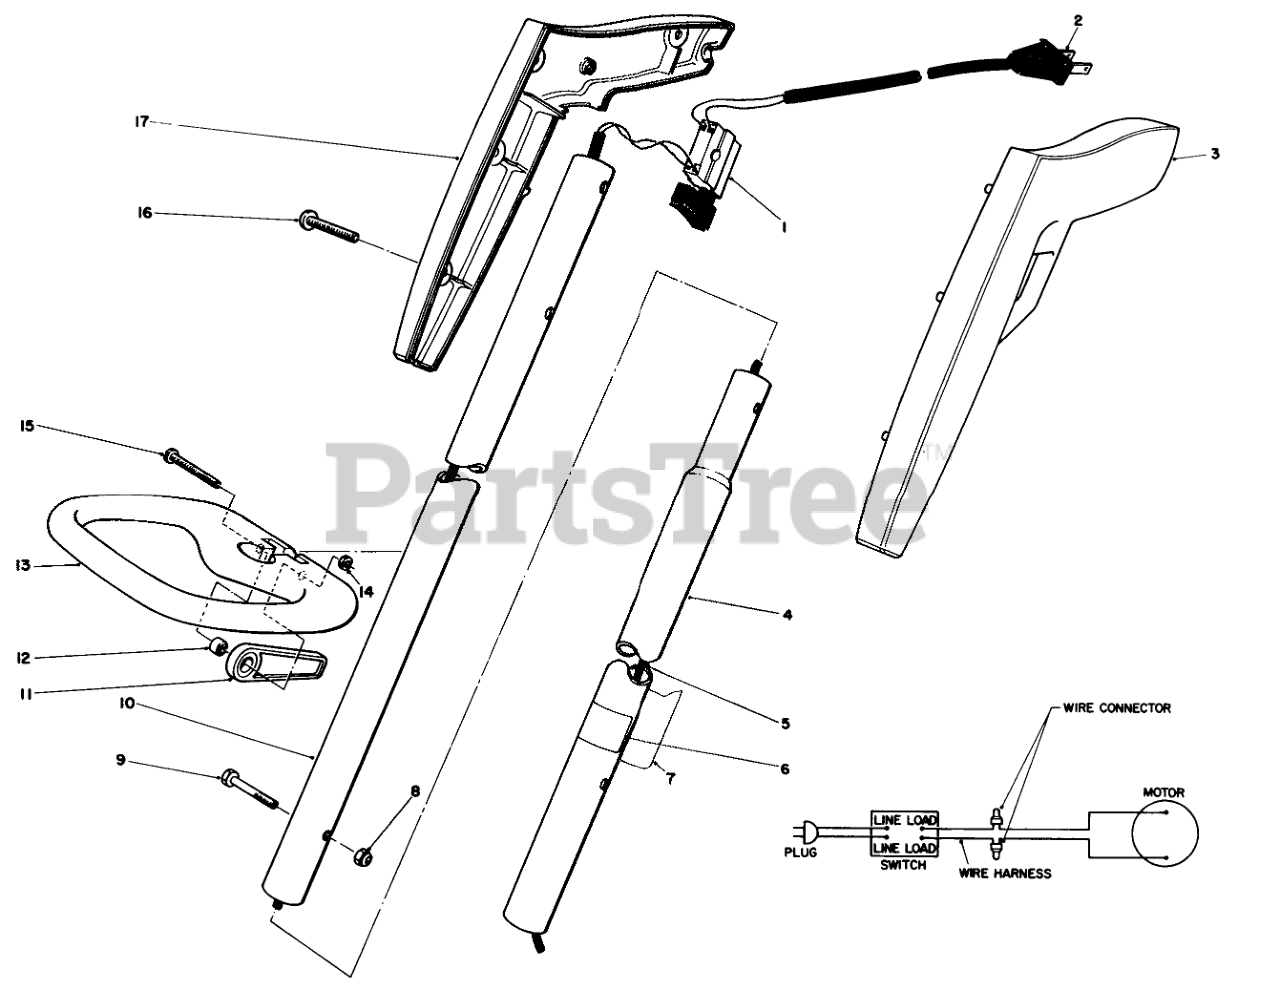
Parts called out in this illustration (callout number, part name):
1	SWITCH SINGLE SPEED
2	Power Cord
3	Grip L.H.
4	Tubing-Lower Extension
5	Wire Harness
6	REP. SERIAL PLT
7	Decal
8	NUT-LOCK, NI
9	HEX HD MACHINE SCREW
10	Oil Button
11	Cam Lock
12	Spacer
13	Support Handle
14	NUT-HEX
15	Screw
16	Screw
17	R.H. GRIP
